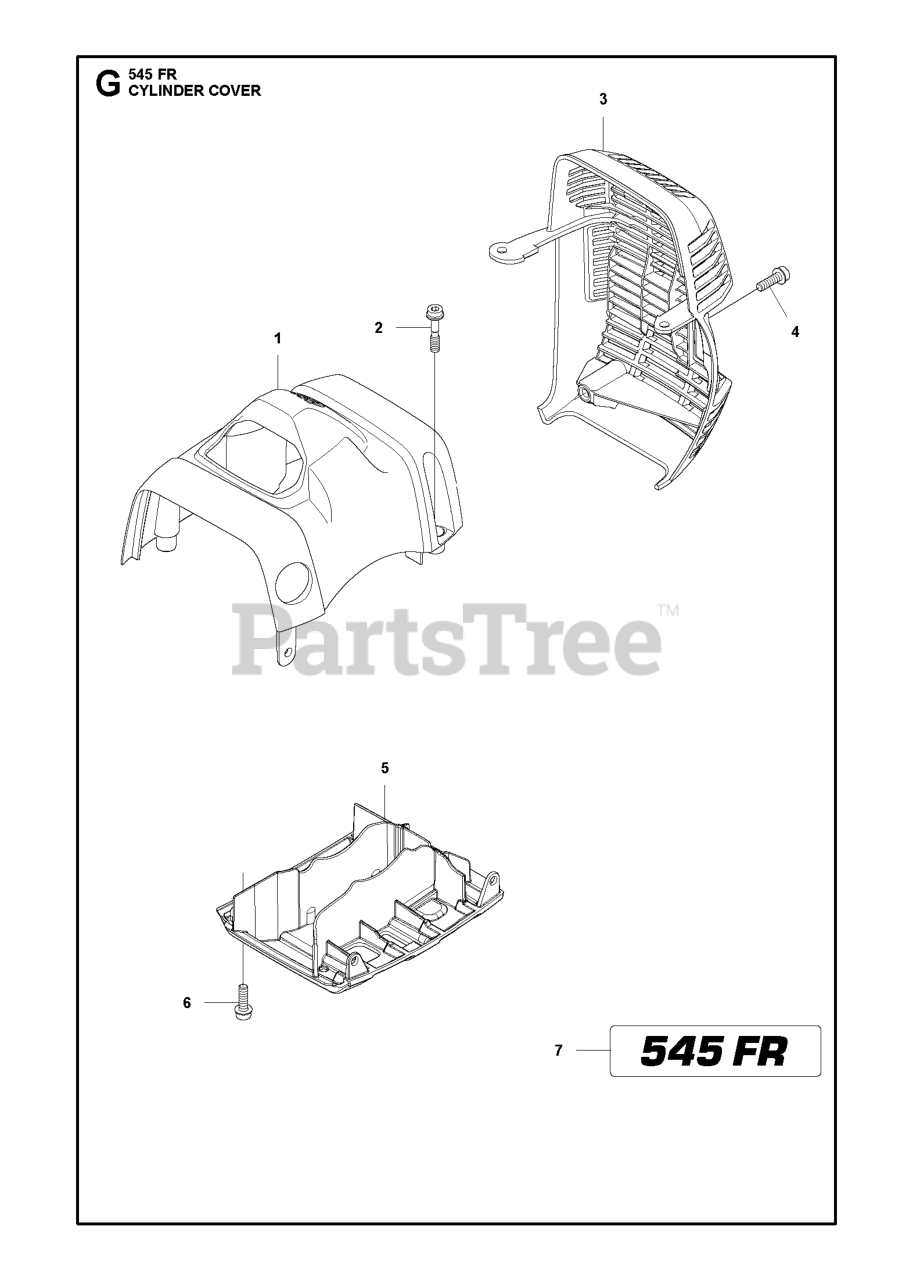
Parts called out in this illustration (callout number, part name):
1	CYLINDER COVER
2	SCREW IHSCFMO
3	HEAT PROTECTOR
4	SCREW IHSCFM
5	PROTECTIVE COVER
6	SCREW IHSCFM
